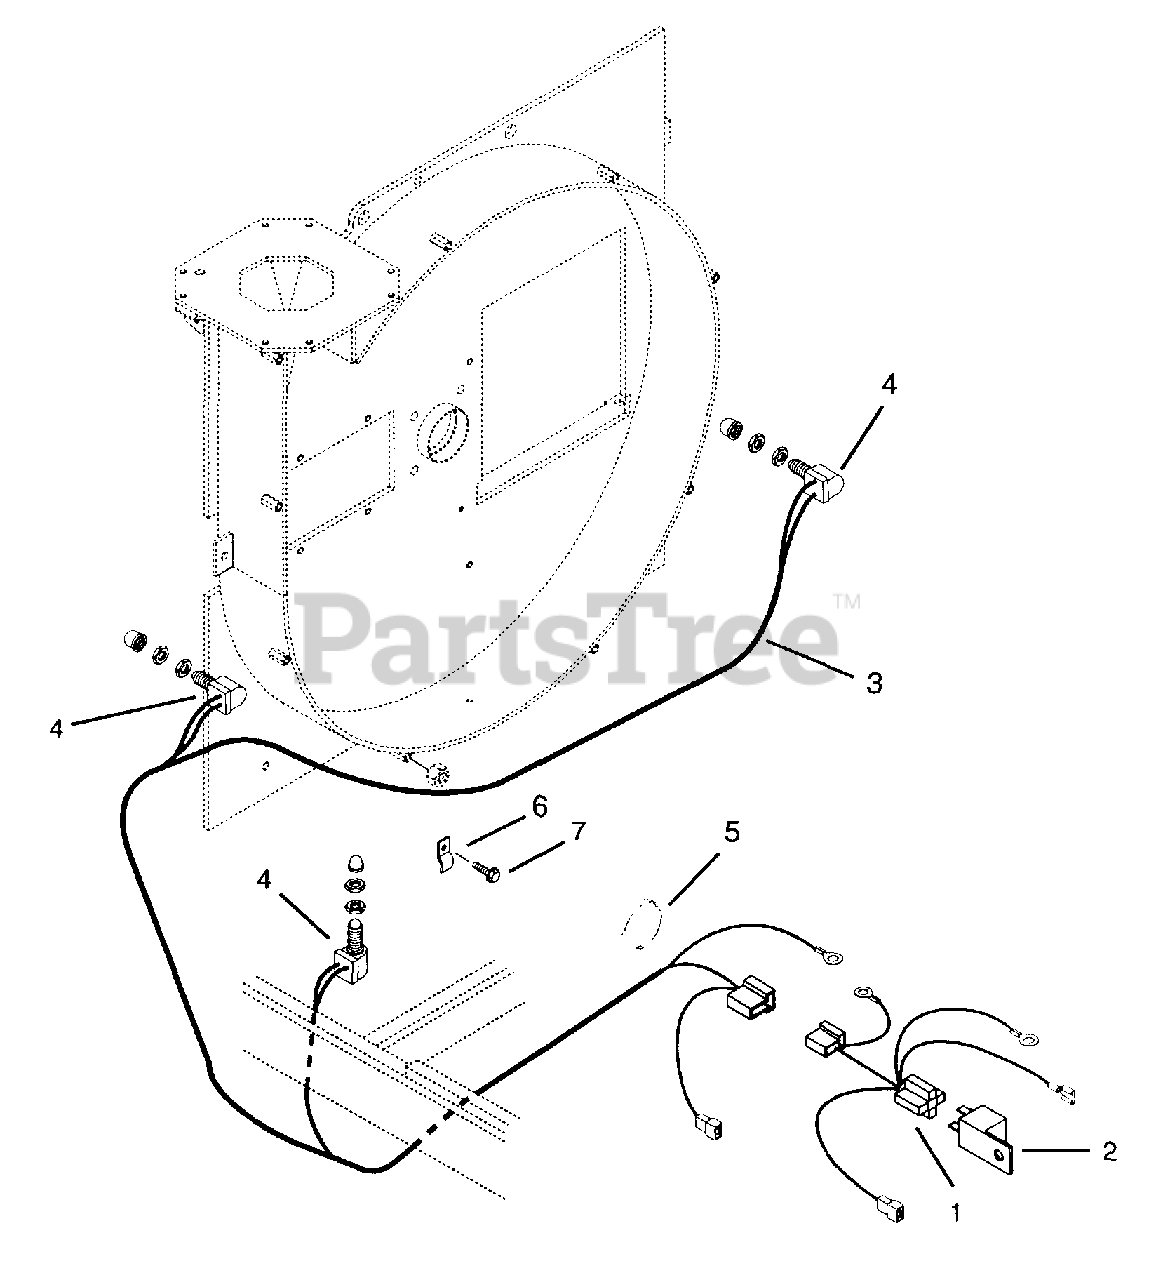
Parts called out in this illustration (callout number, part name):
1	Harness-Relay / Safety
1	Harness-Adapter Safety Switch
2	Relay
3	Harness-Wiring, Safety Switch
4	Safety Switch
5	Cable Tie
7	Screw-Tapping-Hex Washer Head .25-20 x .50
